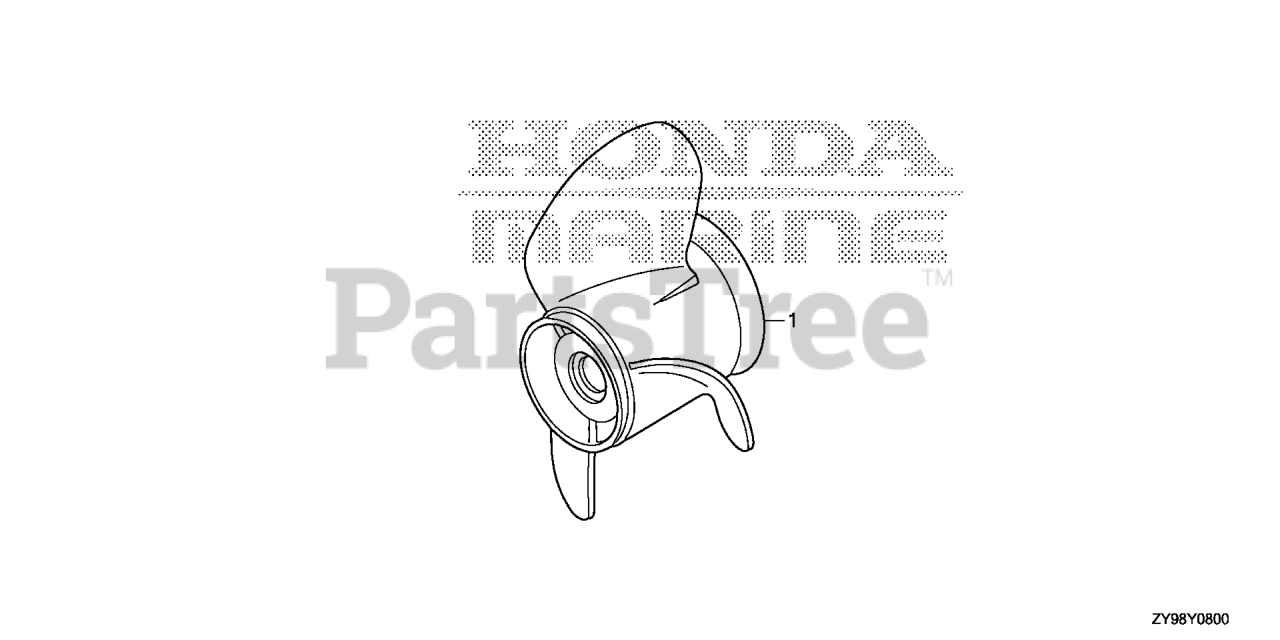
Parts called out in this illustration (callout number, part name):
1	PROPELLER, THREE-BLADE (13X19) (SUS) Use from Frame SN 1302132.
1	PROPELLER, THREE-BLADE (13X21) (SUS) Use from Frame SN 1302132.
1	PROPELLER, THREE-BLADE (14X11) *NH283* (AL) Use from Frame SN 1302160.
1	PROPELLER, THREE-BLADE (13-3/4X13) *NH283* (AL) Use from Frame SN 1302160.
1	PROPELLER, THREE-BLADE (13-1/2X15) *NH283* (AL) (STIN GRAY)
1	PROPELLER, THREE-BLADE (13-1/4X17) *NH283* (AL) Use from Frame SN 1302160.
1	PROPELLER, THREE-BLADE (13X21) *NH283* (AL) Use from Frame SN 1302160.
1	PROPELLER, THREE-BLADE (13X19) *NH283* (AL) (STIN GRAY)
1	PROPELLER, THREE-BLADE (13-1/4X17) (SUS) Use from Frame SN 1302160.
1	PROPELLER, THREE-BLADE (13-1/4X15) (SUS/HAC)
1	PROPELLER, THREE-BLADE (13-1/4X17) (SUS/HAC)
1	PROPELLER, THREE-BLADE (13-1/4X19) (SUS/HAC)
1	PROPELLER, THREE-BLADE (13-1/4X21) (SUS/HAC)
1	PROPELLER, THREE-BLADE (13-1/2X14) *NH283* (STIN GRAY)
1	PROPELLER, THREE-BLADE (13-1/5X19) *NH283* (STIN GRAY)
1	PROPELLER, THREE-BLADE (13-1/5X21) *NH283* (STIN GRAY)
